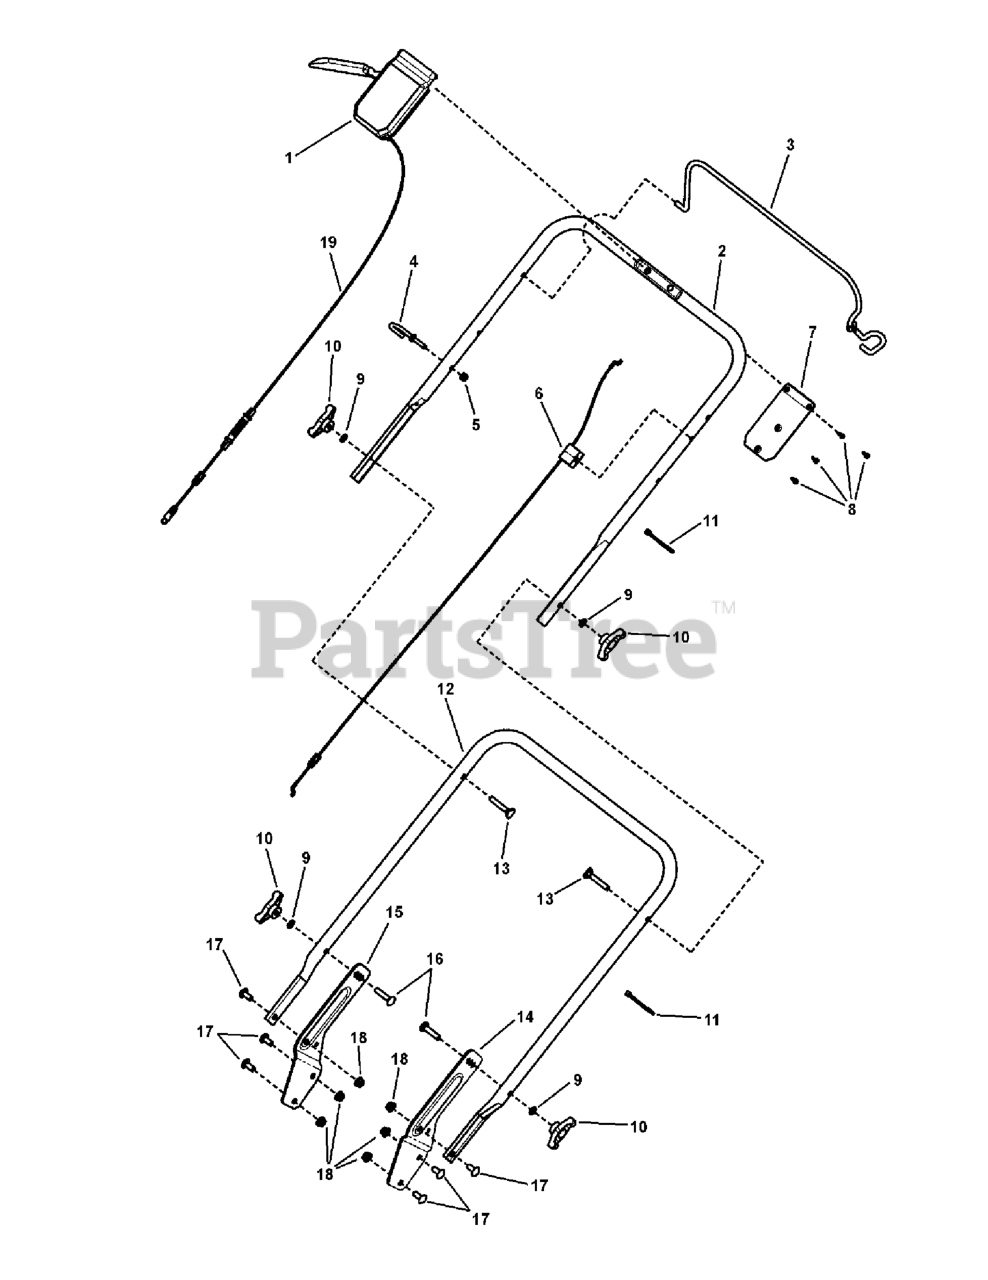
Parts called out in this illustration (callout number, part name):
1	ASSEMBLY, Control Head, Single Speed, Brute
2	HANDLE, Upper, Propelled
3	BAIL, OPC Propelled Brute
4	GUIDE, Rope (1/4-20 thread)
5	NUT, 1/4-20 Hex Nyloc
6	CABLE, Bail, 22" Walk-Behind Mower
7	PLATE, Control Panel
8	SCREW, #8-16 Torxplus Recessed Pan Head, Twin Helix
9	WASHER, 5/16" Internal Tooth lock
10	KNOB, 5/16-18 Wing (Black)
11	WIRE TIE, 11 Inch Std Black Nylon
12	HANDLE, Lower 21" RD
13	BOLT, 5/16-18 x 2" Curved Head Square Neck, GR 2
14	BRACKET, Lower Handle, LH, 21" WBM, RD
15	BRACKET, Lower Handle, RH, 21" WBM, RD
16	BOLT, 5/16-18 x 1-1/2" Round Head Square Neck, YZ
17	BOLT, 5/16-18 x 3/4" Round Head Short Square Neck, GR 5, YZ
18	NUT, 5/16-18 Hex Flange lock, YZ
19	CABLE, DRIVE
